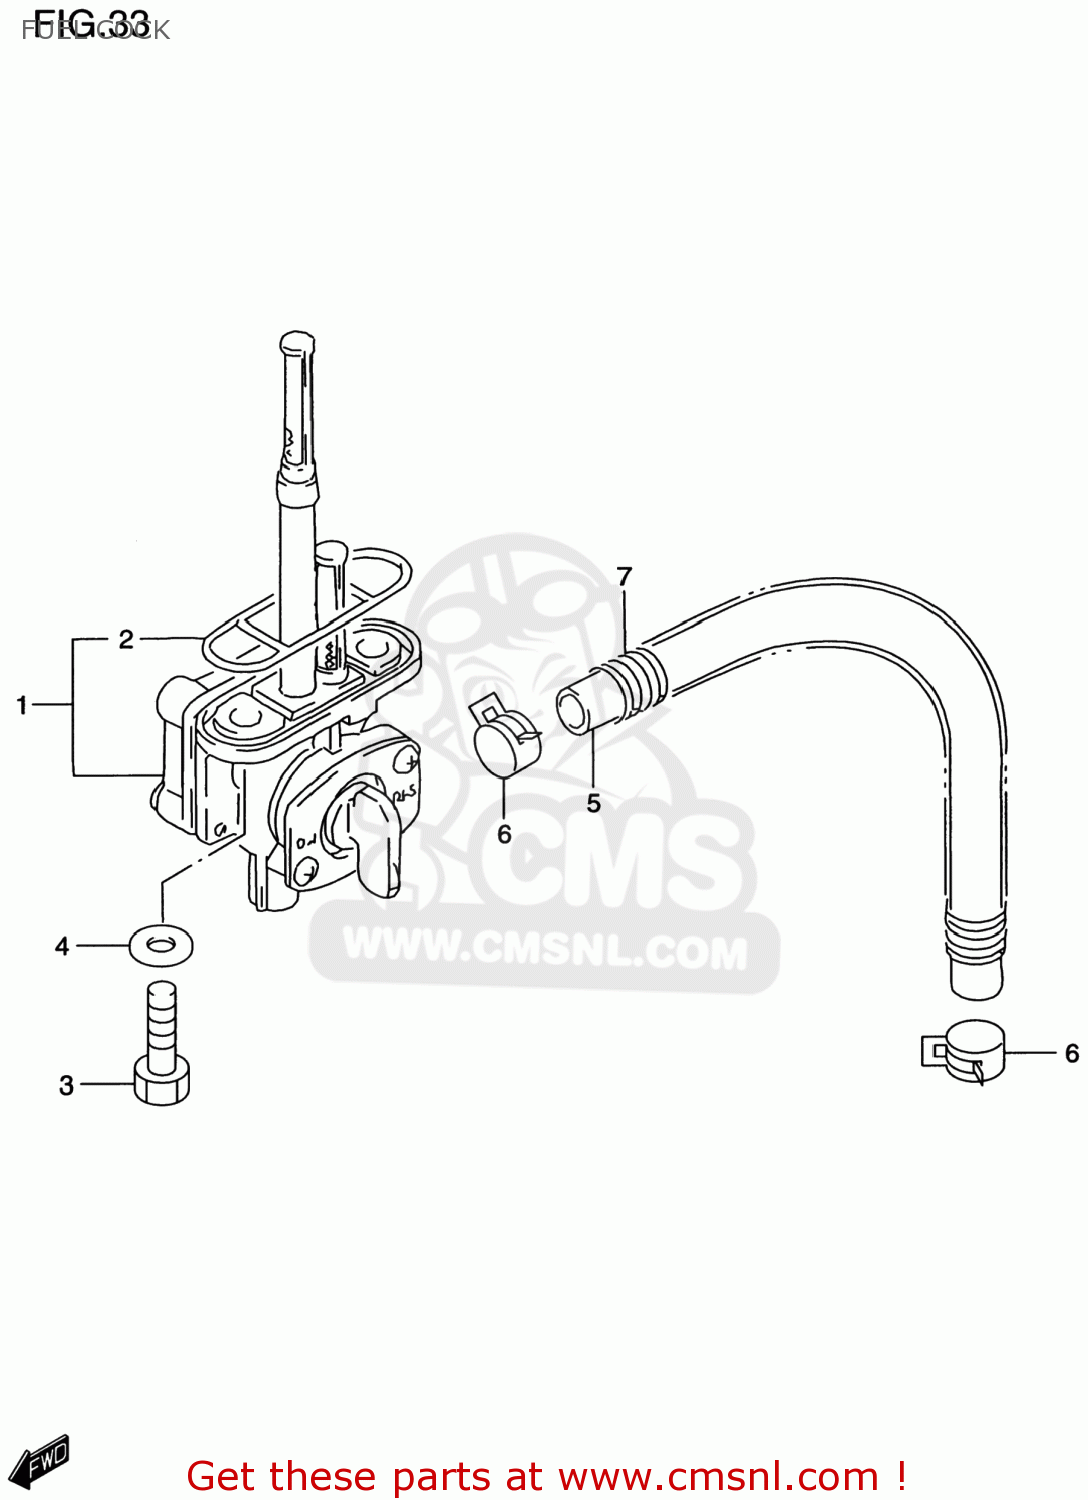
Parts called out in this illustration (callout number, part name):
1	COCK ASSY,FUEL
2	GASKET,JOINT (NAS)
3	BOLT(6X20)
4	GASKET(6.4X11.5X0.8) (NAS)
5	HOSE(7X12X600)
6	CLIP
7	SPRING
